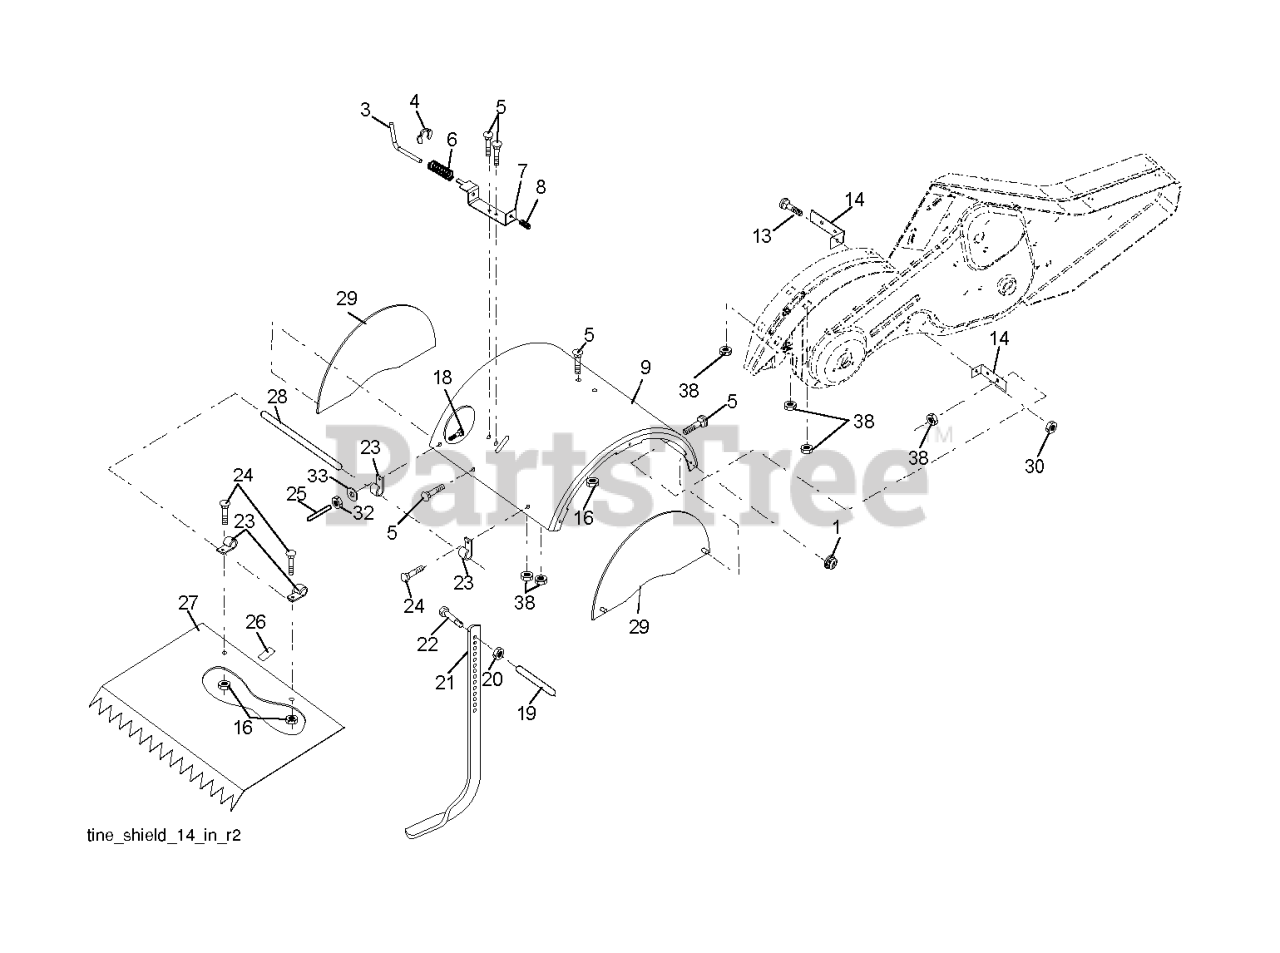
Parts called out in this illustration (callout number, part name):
1	NUT LOCK HEX FLANGE 5/16-18
3	STAKE PIN TI
4	RING, KLIP
5	BOLT, RDHD SQNK 5/16-18 X 3/4
7	BRACKET.LATCH.STAKE.3.20.BLACK
8	SPRING CRT
9	SHIELD.TILLER.TINE.ORANGE
13	BOLT.CARRIAGE.5/16-18
14	BRACKET.TINE.SHIELD.TILLER
16	NUT T
20	NUT.HEX.3/8-16UNC
21	STAKE.DEPTH.16.CRT.BLACK
22	BOLT.375-16
25	VINYL CAP TI
26	PAD IDLER TI
27	SHIELD.PNT.LEVEL.CRT.14.MS-668
28	PIN.HINGE.TILLER
29	SHIELD.ASM.SIDE.ORANGE.(OLD)
30	LOCKNUT-FLANGE 5/16-18
32	NUT
33	LOCKWASHER
38	NUT
